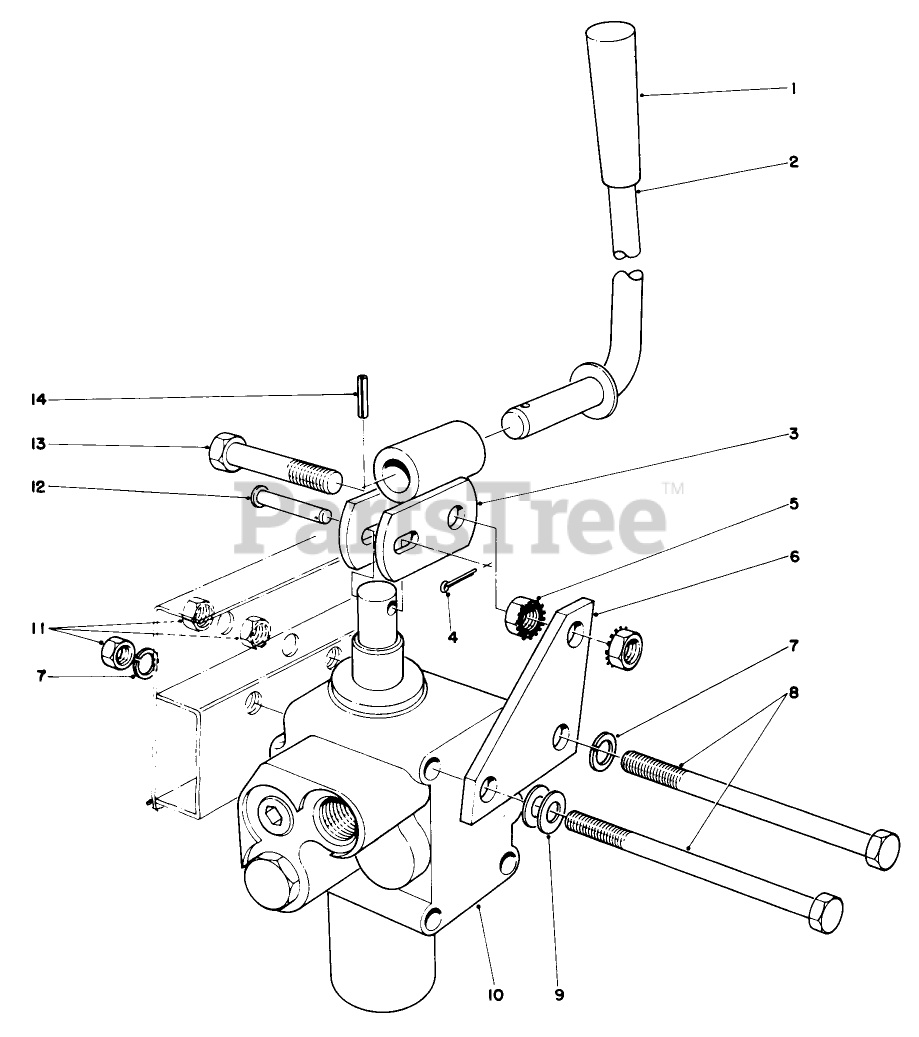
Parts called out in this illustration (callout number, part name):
1	KNOB-CONTROL
2	Lever-Valve
3	Valve Lever Link
4	PIN-COTTER
5	NUT-KEPS
6	Wheel Bolt
7	WASHER-LOCK
8	SCREW-HH
9	WASHER-FLAT
10	VALVE ASM
11	NUT-HEX
12	PIN-CLEVIS
13	SCREW-HH
14	PIN-ROLL
